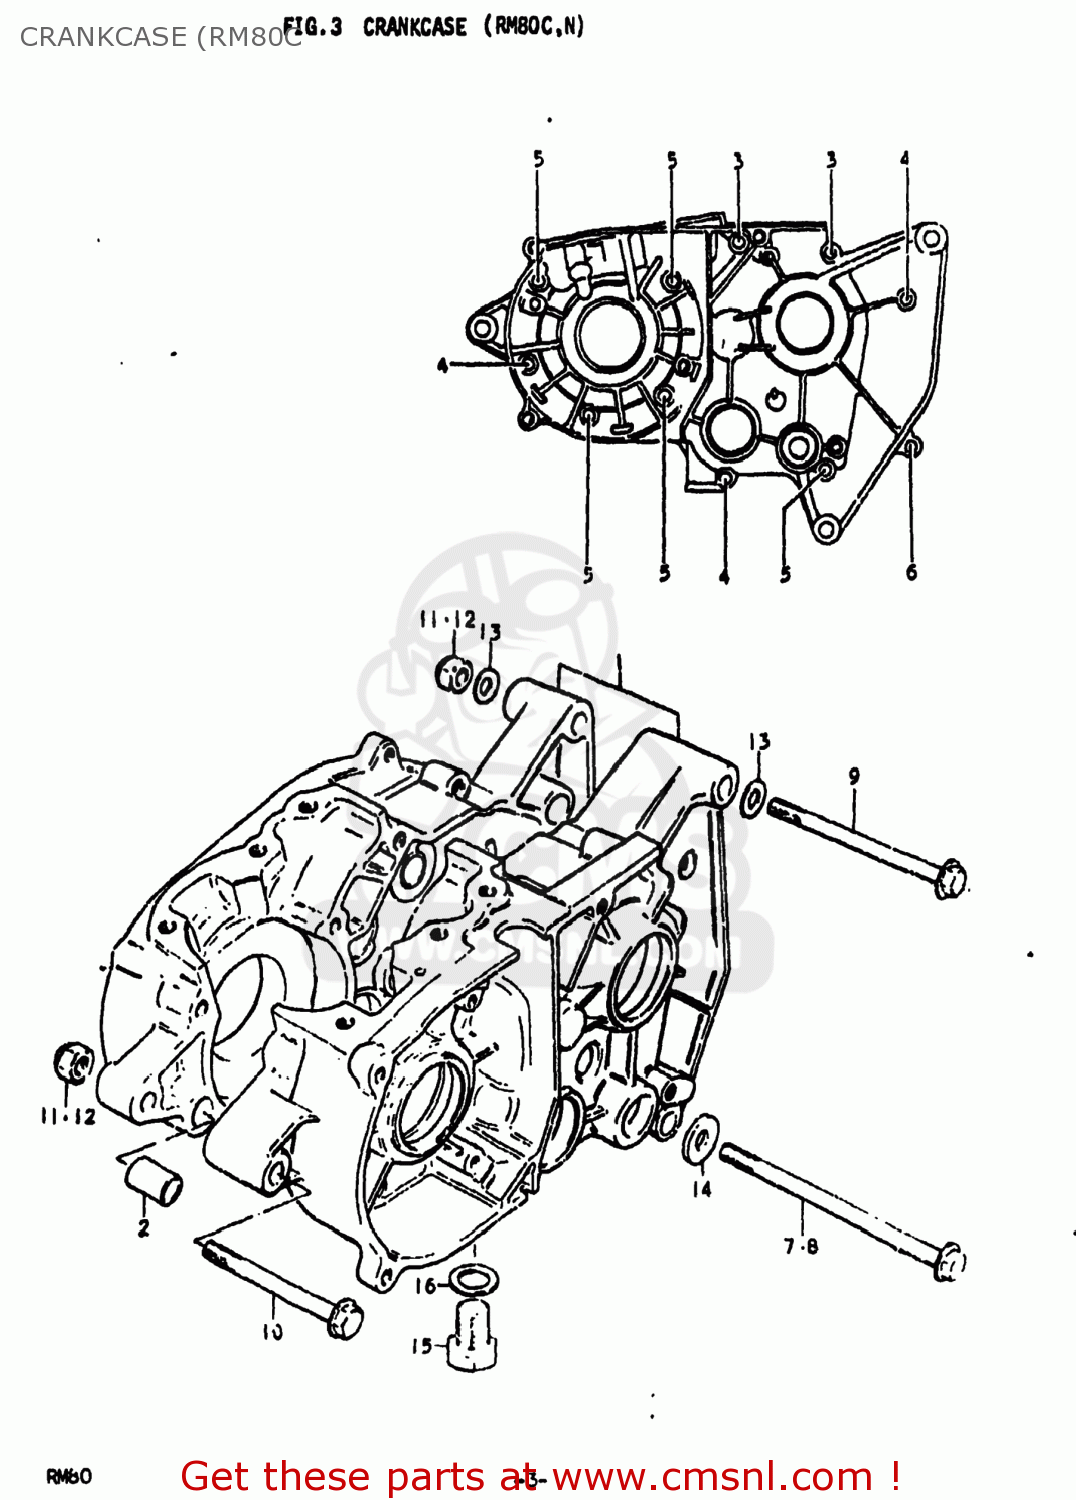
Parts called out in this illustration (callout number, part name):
1	CRANKCASE SET
2	PIN
3	CROSS SCREW (6 X 75)
4	SCREW
5	SCREW (6X35)
6	SCREW
7	BOLT
8	BOLT 8X115
9	BOLT
10	BOLT 8X75
11	NUT
12	NUT
13	WASHER
14	WASHER
15	BOLT 10X20
16	GASKET(10X14X3.6) (NAS)
